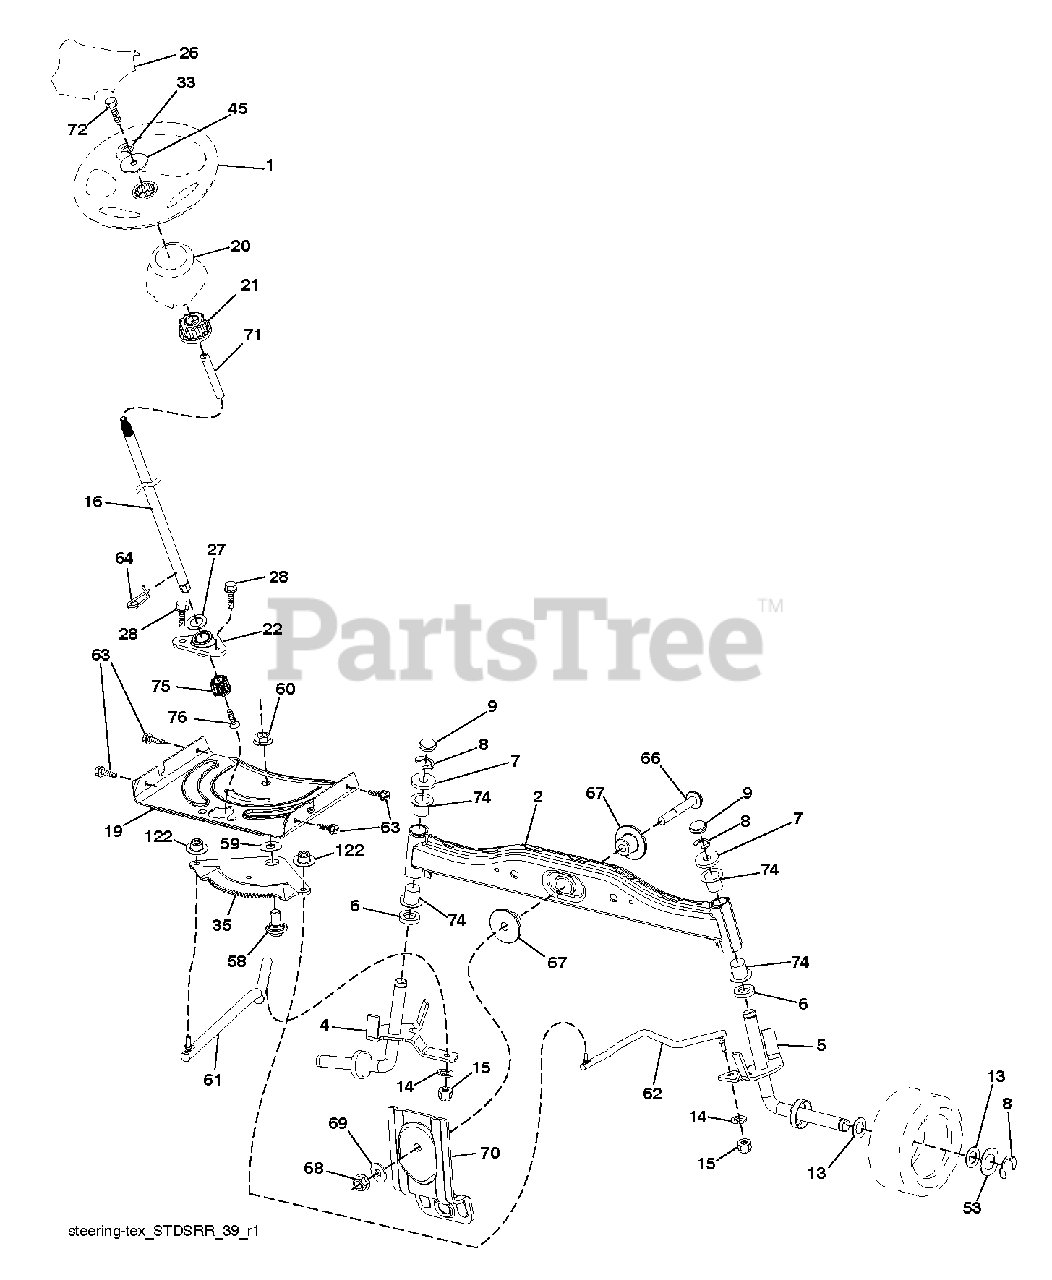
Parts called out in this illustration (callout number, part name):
1	WHEEL.STEERING.HUSQ.PREM.HRDRM
2	AXLE HALF ASM-WELDED
4	SPINDLE.WELDED.LH.15"TEX
5	SPINDLE.WELDED.RH.15"T
6	THRUST WASHER
9	CAP.SPINDLE.BLACK
14	WASHER, LOCK 3/8
15	NUT CROWNLOCK 3/8-24
16	3 HIGH.SHAFT-ZINC.PLATED
19	PLATE.STEER.DDL.NLT/NG
20	STEERING.BOOT.HUSQ.LT
21	ADAPTER, WHEEL STNG..
22	BEARING.SHAFT.STEER.LOWER.625
26	INSERT.CAP.WHL.STRG.HUSQ.PREM
28	SCREW, 3/8-16X3/4
33	LOCKWASHER
35	GEAR.SECTOR.PLATE.DDL.
45	WASHER.11/32
53	WASHER.HARDENED
58	BOLT.SHOULDER.SECTOR.P
59	WASHER.THURST.SECTOR.S
60	NUT FLANGE LOCK 5/8-11
61	DRAGLINK.LH.BALLSTUD.D
62	DRAGLINK.RH.BALLSTUD.D
63	SCREW
64	RETAINER.CLIP.SPRING.S
66	BOLT HEX FGHD 7/16-14 X 3 SERR
67	BUSHING.PM.FRONT AXLE
68	NUT.LOCK.FLANGE.7/16
69	WASHER.1.5X.505X.118
70	BRACKET.FRT.DECK.SUSP.RR.MT431
71	SHAFT.EXTEN.STRG.SPLINE
72	BOLT 5/16-18 X 4 W/PATCH
74	BRNG T
75	PINION.ZINC PLATED
76	SCREW HEAD SOCKET LRVB
122	CAP.GEAR.SECTOR.TEX
